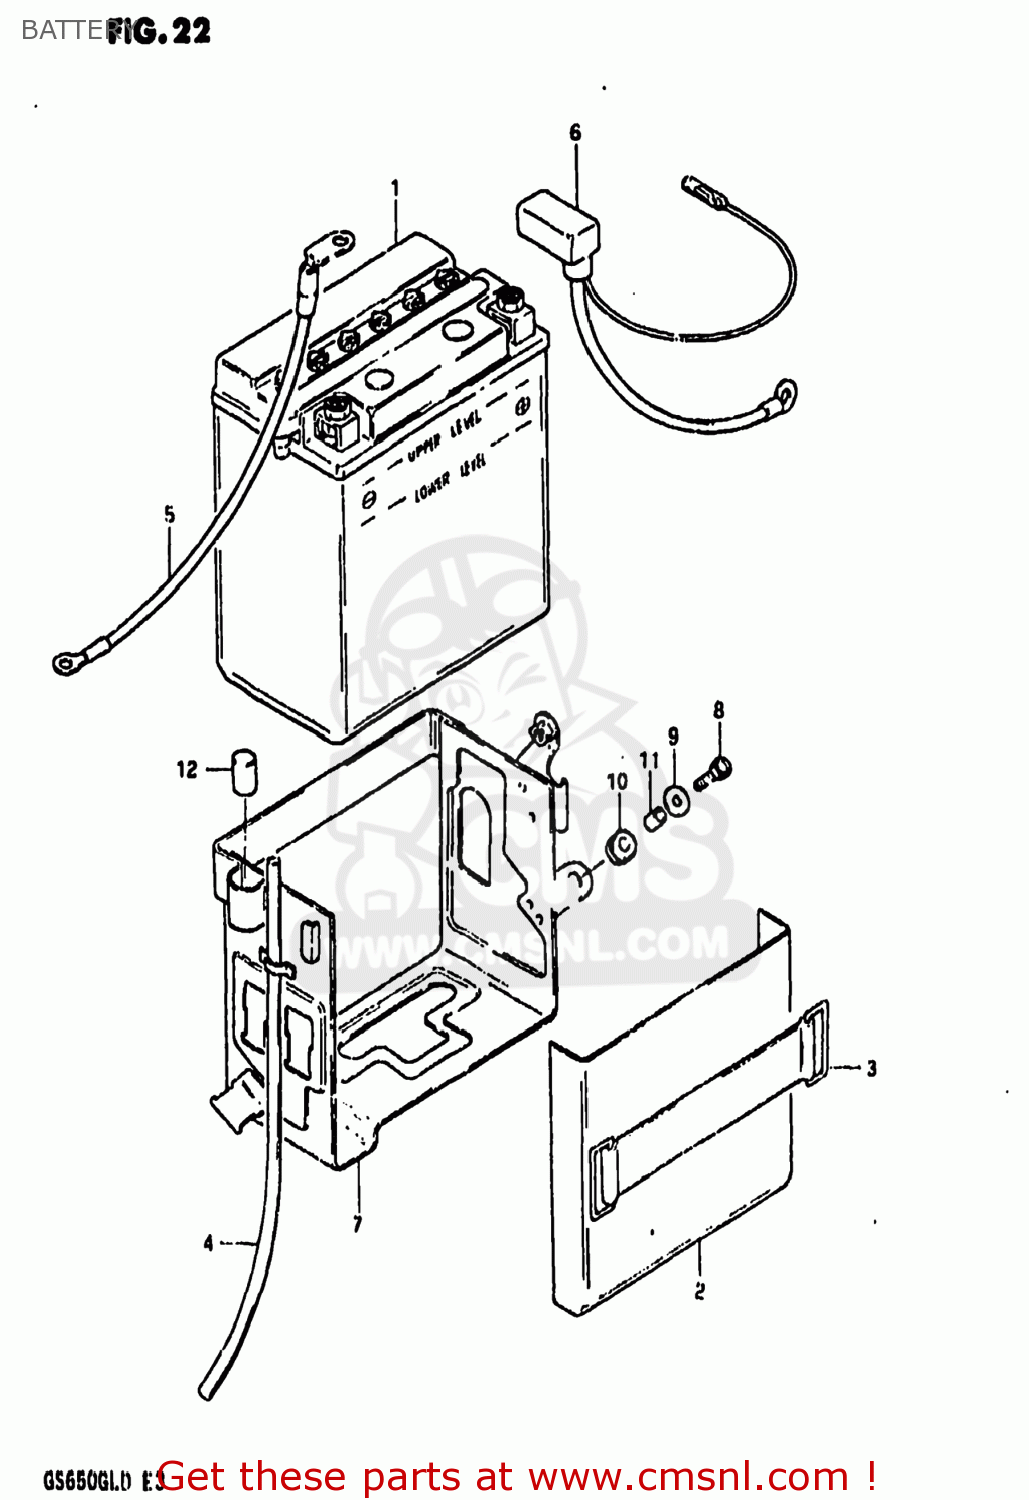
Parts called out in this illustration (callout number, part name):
1	BATTERY ASSY (12V)
2	COVER,BATTERY
3	BAND
4	HOSE,BATTERY EXHAUST
5	CORD,BATTERY MINUS
6	CORD,BATTERY PLUS
7	HOLDER,BATTERY
8	BOLT
9	WASHER
10	CUSHION
11	SPACER(6.1X9X7.5)
12	CUSHION
